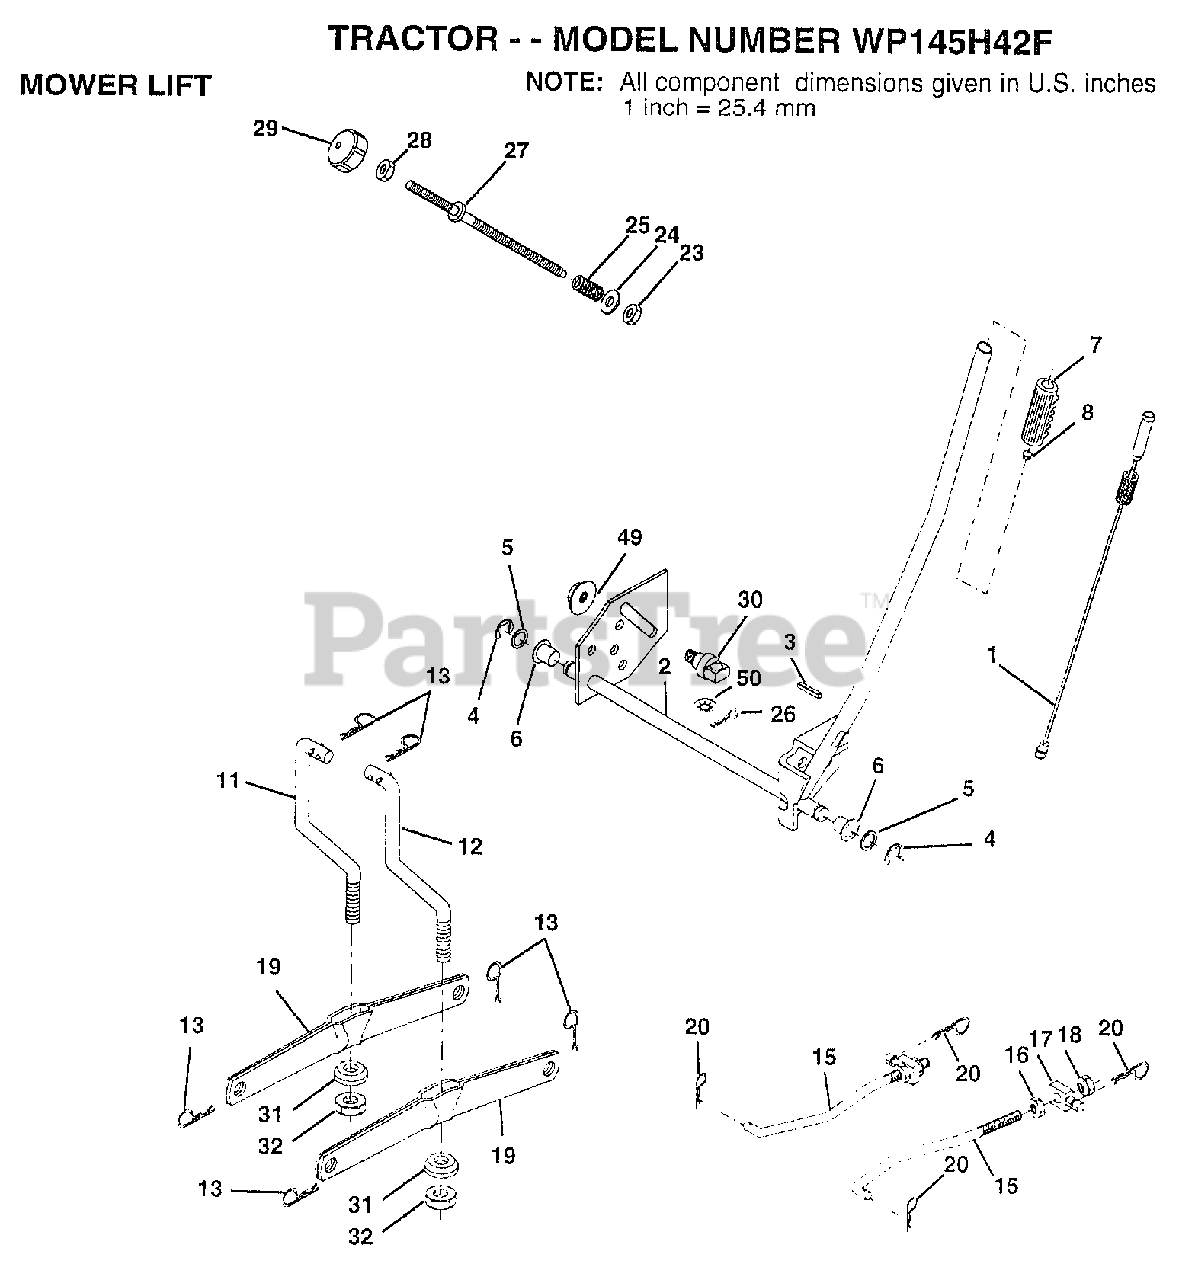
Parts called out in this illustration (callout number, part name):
1	WIRE.ASM.INNER.SP
2	"SHAFT AMS LIFT,RH"
3	PIN GROOVE
5	WASHER
6	NYLON BEARING
7	GRIP
15	LINK.FRONT
16	NUT
17	TRUNION
18	NUT LTV
19	ARM SUSP REAR
20	RETAINER SPRING
23	NUT T
24	WASHER
25	SPRING.COMP.INF.H
27	ROD.ADJ.LIFT
28	NUT
29	KNOB INF 3/8-16
30	TRUNNION
31	BEARING PVT LH
32	NUT.CROWNLOCK.3/8
49	NUT.HXFLG.LOCK.
